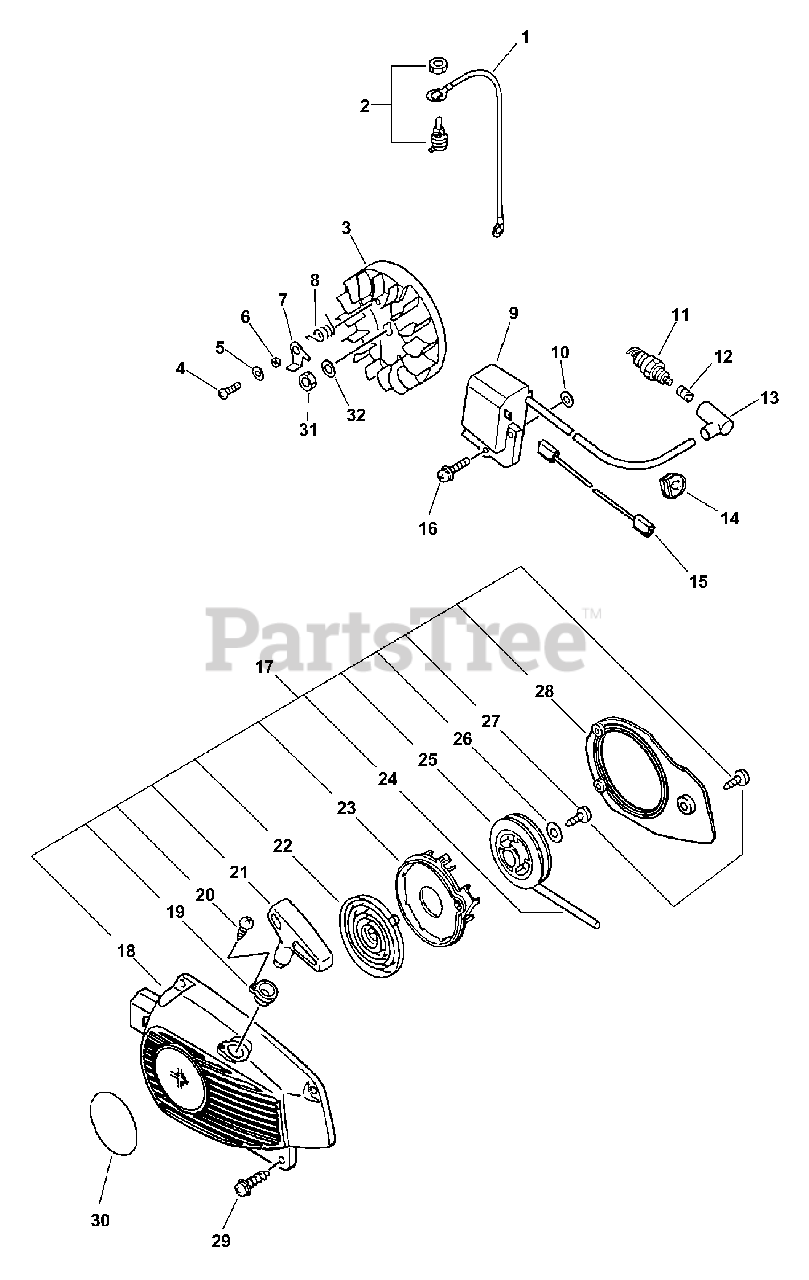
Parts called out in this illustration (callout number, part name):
1	LEAD - GROUND L= 100
2	SWITCH, ON-OFF
3	FLYWHEEL
4	SCREW 5×12
5	WASHER 5.5×12×0.8
6	SPACER 5.2×8×2.1
7	PAWL, STARTER
8	SPRING, TORSION
9	COIL, IGNITION
10	WASHER 5.2×12×3
11	SPARK PLUG - BPM8Y
11	SPARK PLUG - BPMR8Y
12	TERMINAL, SPARK PLUG
13	CAP, SPARK PLUG
15	LEAD - IGNITION L= 95
16	SCREW 5×22
17	STARTER ASSY
18	CASE, STARTER
19	GUIDE, ROPE
20	SCREW 3×14
21	GRIP, STARTER
22	SPRING, RECOIL
23	PLATE, STARTER
24	ROPE, STARTER 3.0×850
25	REEL, ROPE
26	WASHER 4.1×15.5×1T
27	SCREW 4×14
29	SCREW 4×16
30	LABEL, ECHO
31	NUT M8
31	NUT, FLANGE M8
32	WASHER 8.5×16×1.2
